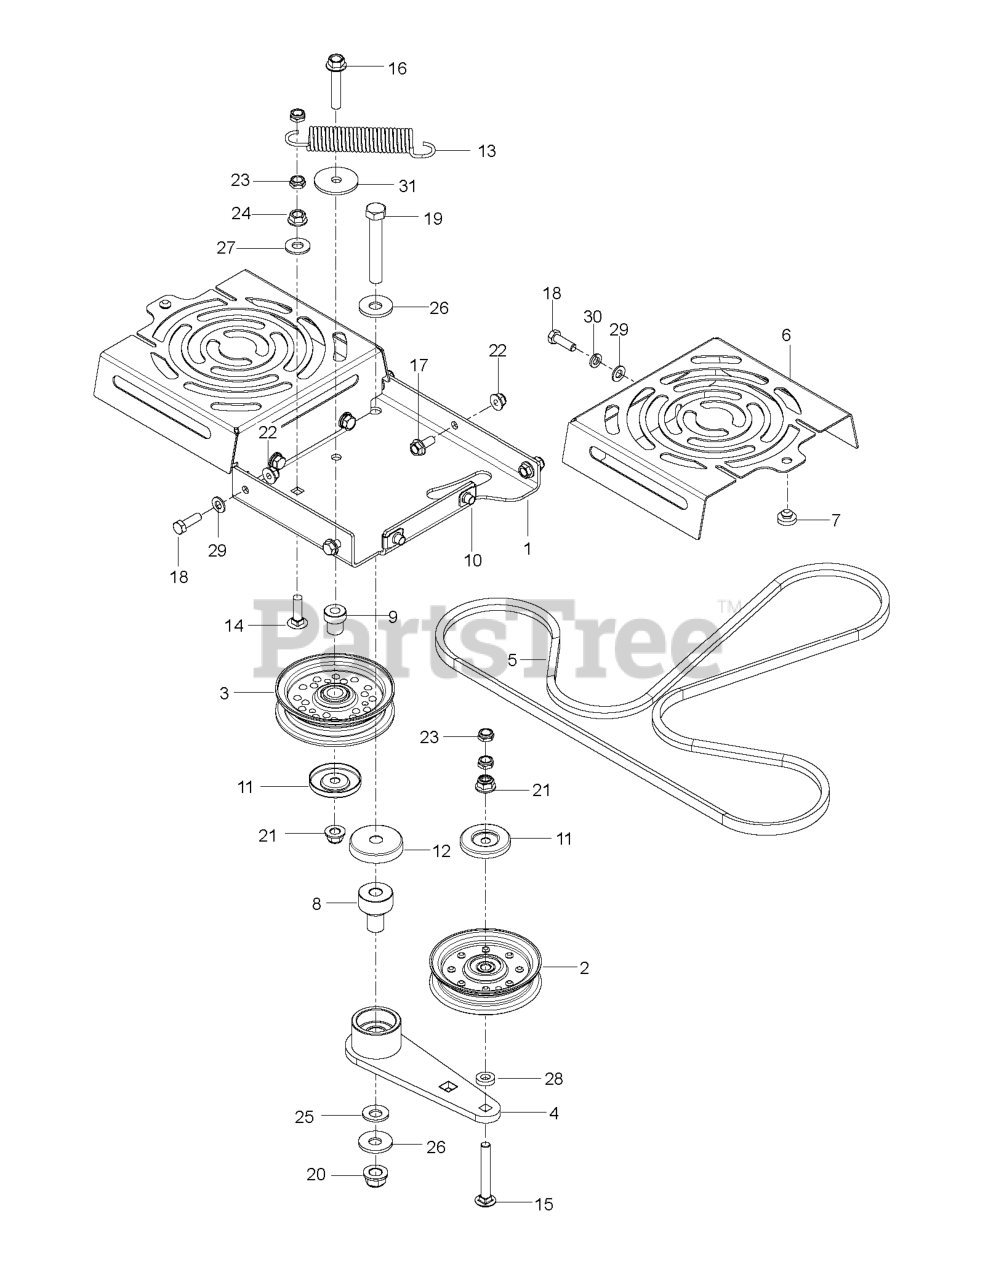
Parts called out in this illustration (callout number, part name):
1	PLATE.PNT.IDLER.SUPPORT.E-DIP
2	IDLER PULLEY
3	PULLEY.IDLER.FLAT.46.PR.DR.
4	ARM, IDLER, STEEL, W/BGS
5	BELT, HYDRO, 3400
6	SHIELD FAN BLACK
7	GROMMET, BUMPER
8	PIVOT, BEARING
9	PIVOT, IDLER
10	U-CLIP 5/16-18 NUT RETAINER
11	DUST SHIELD
12	SHIELD, DUST
13	SPRING, PUMP
14	BOLT.3/8-14X1.25
15	RHSNB 3/8-16 X 2.75
16	HHFS 3/8-16 X 2.0 GD 5
17	HHFS 5/16-18 X 3/4
18	HCS 5/16C X 1
19	HCS 1/2-13 X 3-1/4 GD 5 ZD
20	NUT, 1/2-13 HEX FLG NYLOC ZD
21	NUT 3/8-16 HEX FLG NYLOC ZD
22	5/16-18 NYLOC FLANGE NUT
23	NUT HEX 3/8-16 NYLON, THIN
24	NUT 3/8C WHIZ
25	CONTACT BELLSPR 1/2
26	WASHER.9/16 X 1 3/8 X 12 GA.
27	RP WASHER 3/8 FLAT
28	WASHER 3/8 X 3/4 X .187 TK
29	WASHER
30	WASHER.LOCK.HVY.HLCL.SPR.5/16
31	WASHER, 3/8 SPEC
